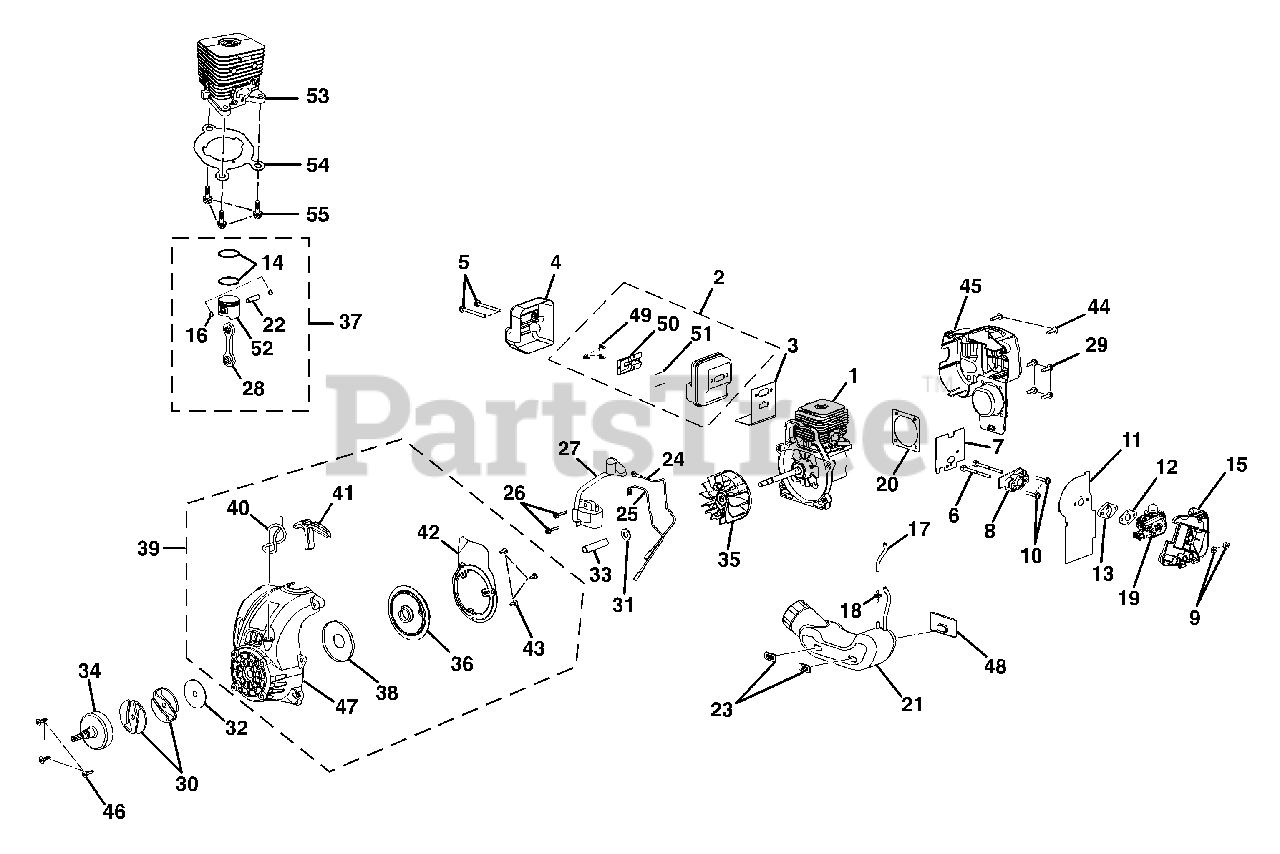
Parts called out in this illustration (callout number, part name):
1	SHORT BLOCK ASSEMBLY
2	MUFFLER ASSEMBLY
3	MUFFLER GASKET
4	HEAT SHIELD
5	SCREW (TORX HD.)
7	HEAT DAM GASKET
8	HEAT DAM
9	LOCK NUT (10-24)
10	SCREW (TORX PAN HD.)
11	CARBURETOR GASKET
12	CARBURETOR GASKET
14	PISTON RING 30CC
15	AIR FILTER BOX
16	RETAINING RING
17	TUBING, RUBBER (63.5 MM)
18	FITTING, INLINE FUEL
19	CARBURETOR
20	GASKET, C/C COVER
21	FUEL TANK W/CAP ASSEMBLY
22	PISTON PIN
24	LEAD W/TERMINALS
26	SCREW (8-32 X 1 in. THREAD FORMING)
27	IGNITION MODULE (W/ 3 SEC. KILL)
28	CONNECTING ROD ASSEMBLY
29	SCREW (10-24 X 3/4 in. PAN HD.)
32	WASHER
34	DRUM & CONNECTOR
35	ROTOR AND PAWL ASSEMBLY
36	PULLEY ASSEMBLY
37	PISTON ASSEMBLY
38	SPRING & CONTAINER
39	COMPLETE STARTER ASSEMBLY
40	STARTER ROPE
41	STARTER GRIP
43	SCREW (8-16 X 1/2 in. THD. FORM.)
44	SCREW (10-14 X 7/8 in. TORX HD.)
45	REAR HOUSING
46	SCREW (10-24 X 3/4 in. TRUSS HD.)
47	STARTER HOUSING W/EYELET
48	RUBBER BUMPER
49	SCREW (6-20 X 1/4 in. TRI-LOBULAR)
50	OUTLET TUBE
52	PISTON W/PINS
53	CYLINDER
54	CYLINDER GASKET
55	SCREW (12-24 X 5/8 in.)
